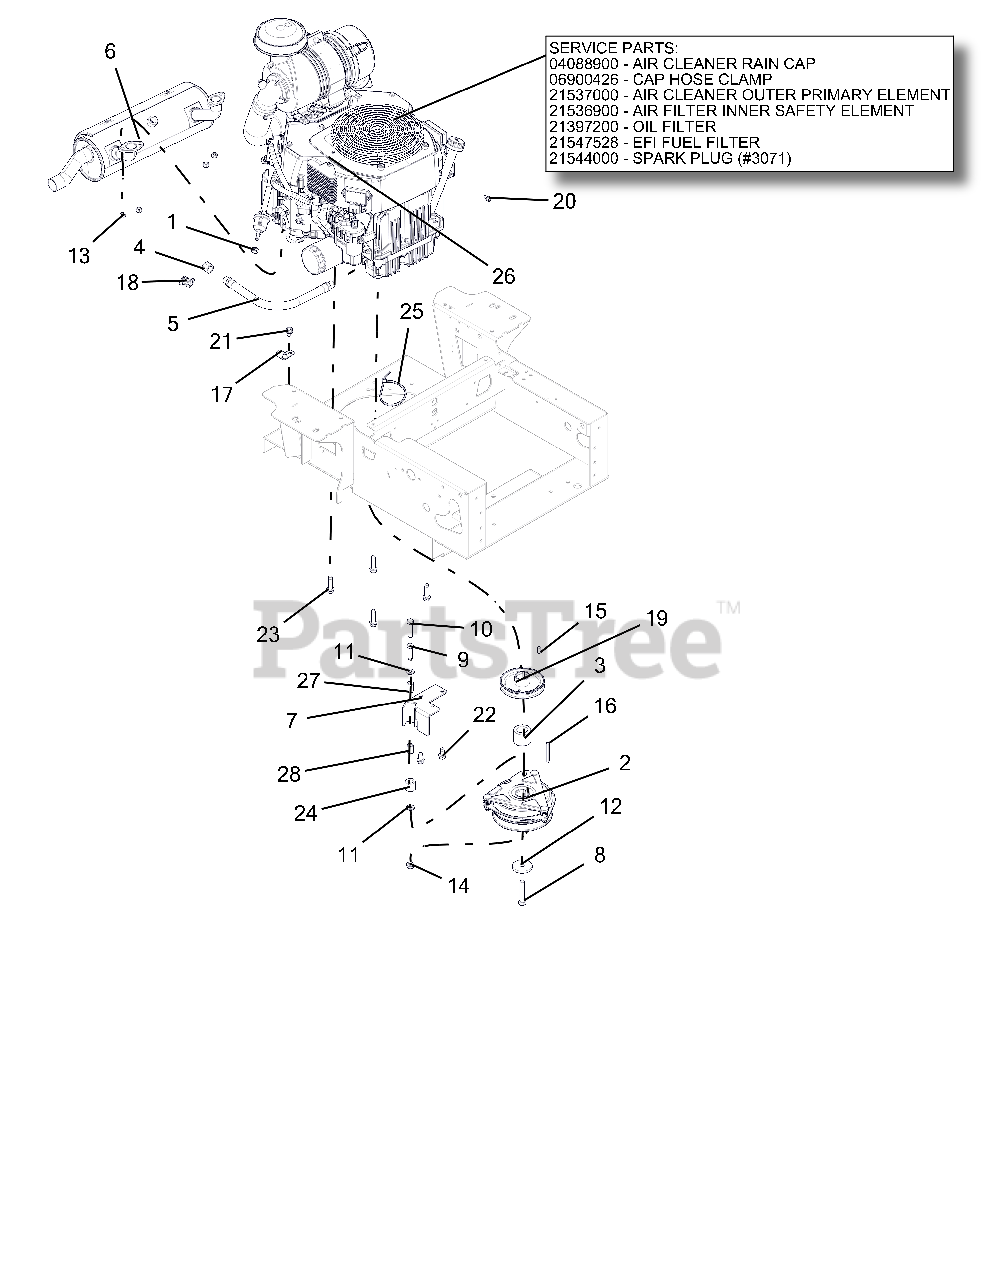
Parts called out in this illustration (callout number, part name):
1	CLAMP, FUEL LINE
2	CLUTCH, OGURA GT2.5-FE02
3	SPCR, 1.125 X 1.75 X 1.400
4	PIPE, CAP 3/8 NPT FEMALE
5	HOSE, HYD .38-11-OK M6N0-M6N0
6	MUFFLER, KOHLER EFI
7	BRKT, CLUTCH STOP
8	BLT-HEX .44-20X2.50 GR5 EP80 YWZC
9	BLT-HEX .38-16X1.50 GR5 YWZC
10	BLT-HEX .38-16X1.75 GR5 YWZC
11	WSHR-FL-STL.406X.812X.065 YWZ
12	WSHR-FL-STL .469X2.00X.25 YWZC
13	NUT-LK-TOP M8-1.25 YWZC
14	NUT, LK-TOP-FLG .38-16 YWZC
15	KEY-SQ .250X.250X.625
16	KEY, .25X.25X2.25
18	CLIP, T, .38-.50
19	PULLEY, 4.50 OD X 1.127 ENGINE-BLACK
20	SCR-TAP .25-20X.50 HWH TR YWZ
21	SCR-TAP .38-16X.50 HWH TR YWZ
22	SCR-TAP .38-16X.75 HWH TR YWZ
23	SCR-TAP .38-16X1.50 HWH TR YZ
24	BUMPER, RUBBER .62 X 1.0 X .88 LG
25	CABLE, TIE 5.50 LG
26	ENGINE, KOHLER EFI ECV740
26	AIR CLEANER RAIN CAP
26	CAP HOSE CLAMP
26	AIR CLEANER OUTER PRIMARY ELEMENT
26	AIR FILTER INNER SAFETY ELEMENT
26	OIL FILTER
26	EFI FUEL FILTER
26	SPARK PLUG (#3071)
27	BUSH.,S.391X.622X.95 ST REV A
28	BUSHING, SLV .407X.625X.813
